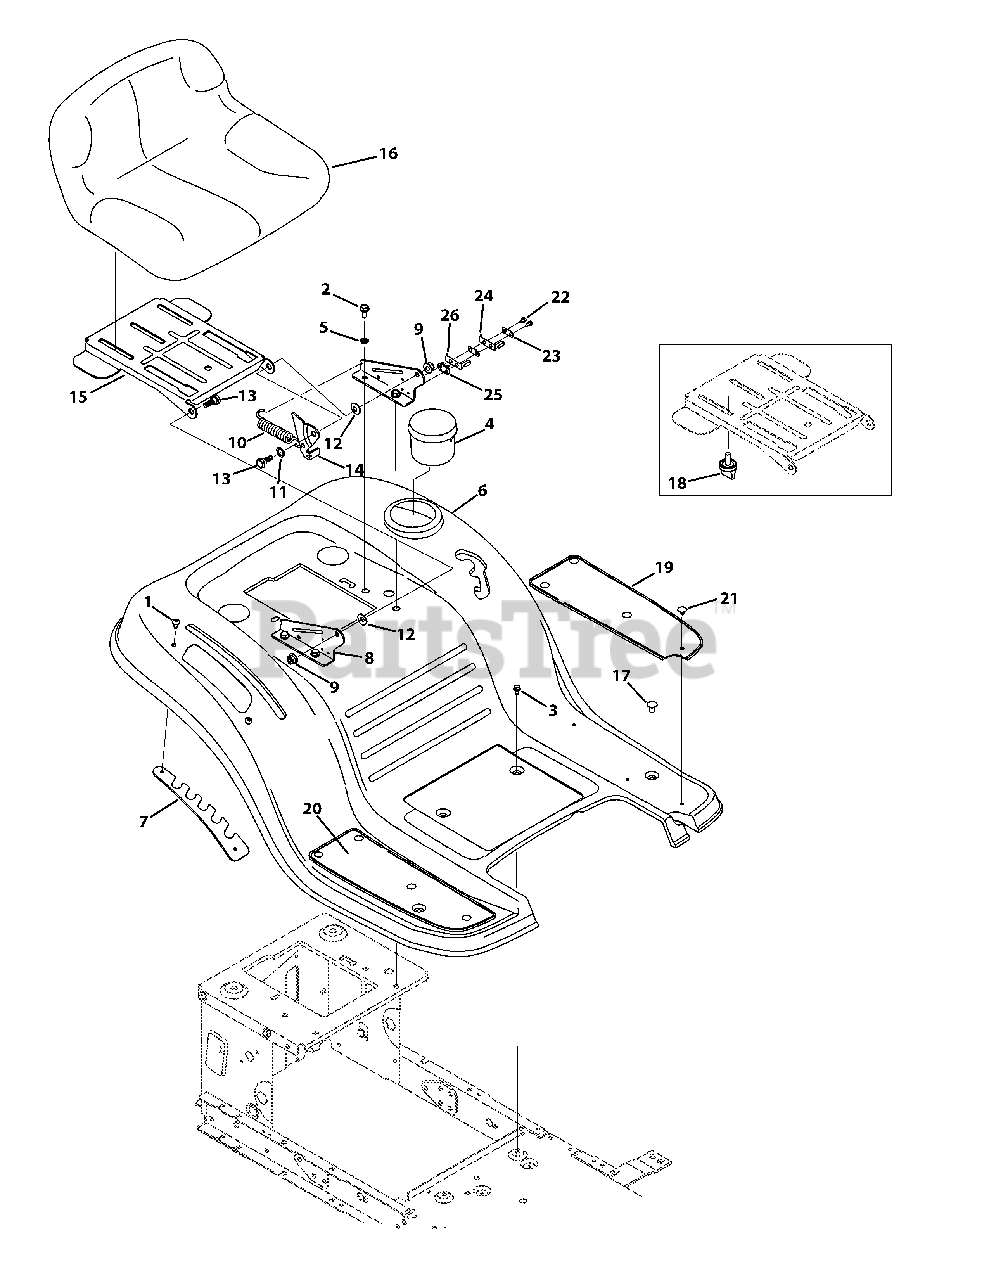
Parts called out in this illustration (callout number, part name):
1	Screw, 1/4-20 x .500
2	Screw, 5/16-18 x .750
3	Screw Pan Torx Head, 1/4-20 x .500
5	Loack Washer, 5/16
6	Fender
7	Lift Adjuster Bracket
8	Seat Mount Bracket
9	Flangelock Nut, 5/16-18
10	Extension Spring
11	Flat Washer, .510x .750 x .033
12	Bell Washer, .340 x .872 x .060
13	Shoulder Screw, 5/16-18 x .437 x .268
14	Lift Seat Bracket
15	Pivot Seat Manual Adjust Bracket
16	Low Back Seat, Black
17	Screw Carriage, 1/4-20 x .62
18	Knob, 3/8-16 x .875
19	Foot Pad, Abrasive, LH
20	Foot Pad, Abrasive, RH
21	Ratchet Clip, .250 x .500
22	Screw, 8-18 x .500
23	Insulator Plate
24	Outer Seat SPring
25	Insulator Boss Plate
26	Inner Seat Spring
